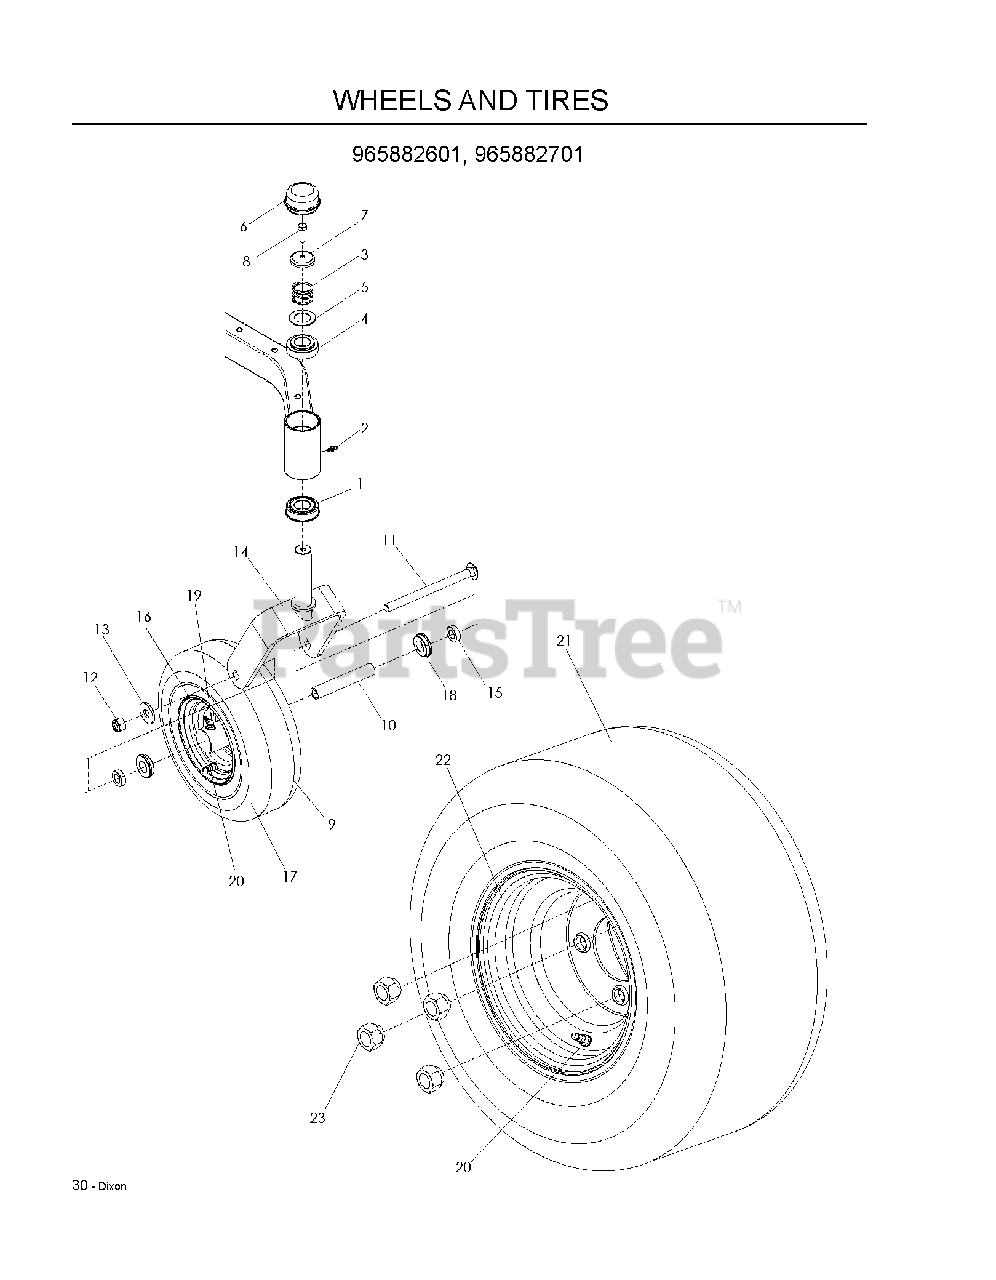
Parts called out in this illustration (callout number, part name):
1	BEARING FLANGED
2	ZERK, 3/16, DRIVE IN
3	SPRING, CASTER
4	BUSHING, CASTER
5	WASHER, 1.025 ID X 1.64
6	GREASE CAP
7	CASTER.PLUG
8	HCS 5/16C X 1
9	TIRE COMPLETE
11	RHSNB 1/2-13 X 6.50 GR2 ZD
12	NUT 1/2-13 HEX NYLOC ZD
13	WASH USS FLAT 1/2
14	CASTER DK BLUE
15	SPACER, 5/16"
17	TIRE - 410/350-5
18	BEARING RETAINER
19	ZERK
20	VALVE STEM TR-412
21	TIRE ASM, 20 X 8-8
22	RIM.8X7.W/8".OFFSET
23	LUG NUT 1/2F
